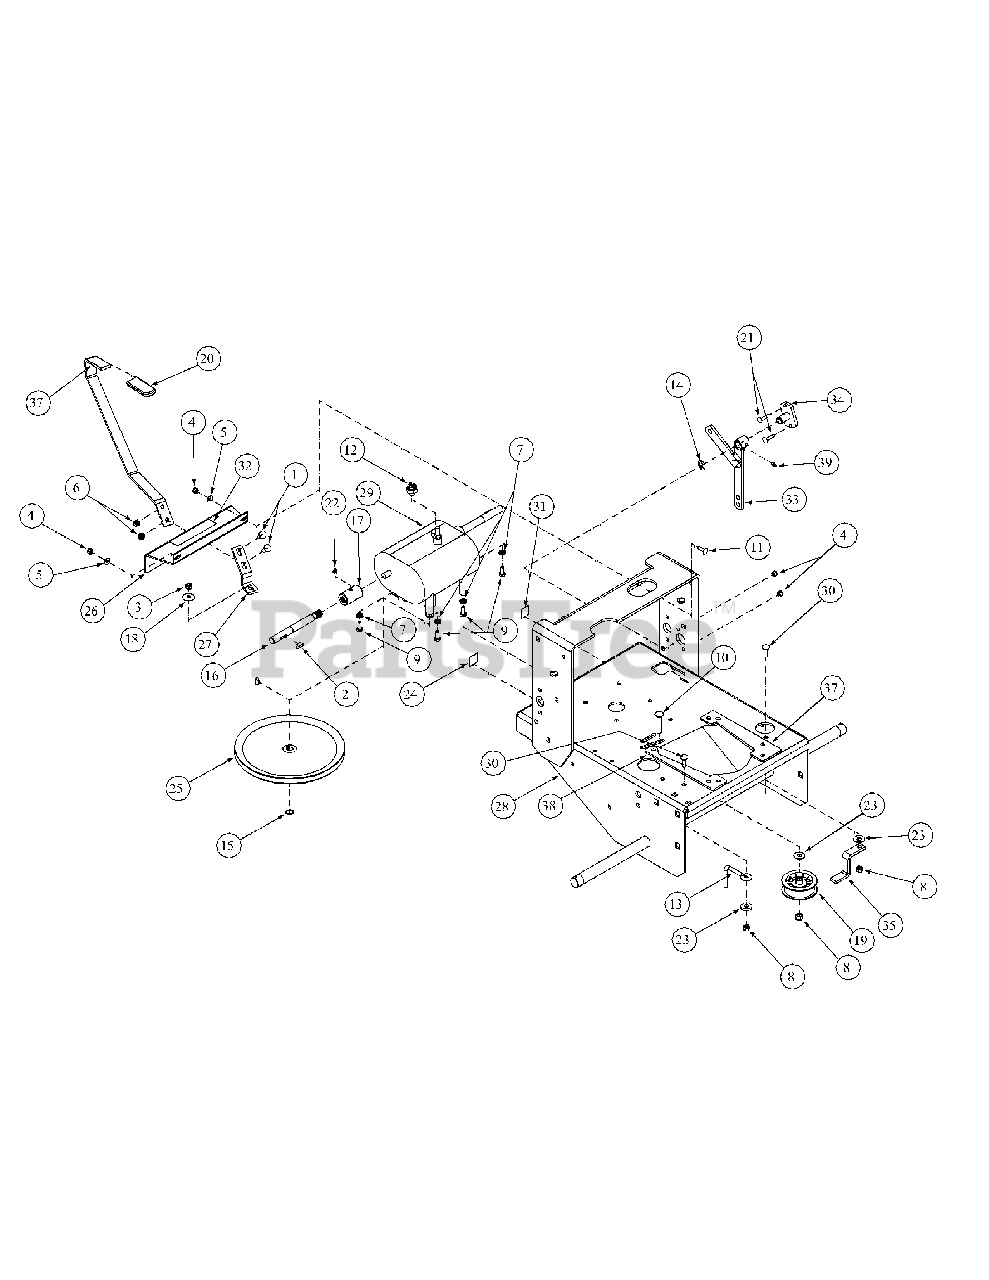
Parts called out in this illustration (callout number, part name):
1	Carriage Bolt, 5/16-18 x 1
2	Woodruff Key, 3/16 x 3/4
3	Jam Nut, Insert Lock, 3/8-24
4	Lock Nut, Nylon Insert, 1/4-20
5	Flat Washer, 1/4 Zinc
6	Nut, 5/16-18 Nylock
7	Lock Washer, 5/16 Zinc
8	Lock Nut, Nylon Insert, 3/8-16
9	Hex Cap Screw, 5/16-18 x 3/4
10	Carriage Bolt, 3/8-16 x2
11	Carriage Bolt, 1/4-20 x .750
12	Switch, WB Transmission
13	Drive Belt Guide
14	E-Ring, 5/8
15	External Retainer Ring
16	Jackshaft w/ Heavy Spline
17	Coupling w/Heavy Spline
18	Bell Washer, .39 ID x 1.13 OD x .062
19	Flat Idler Pulley w/Adapter
20	Grip, .250 x 1 x 3-1/2, Yellow
21	Carriage Bolt, 1/4-20 x 1.00
22	Grease Fitting, 1/4-28 x 3/16
23	Idler Washer
24	Decal "Made In America
25	Transmission Pulley
27	Shift Arm
28	Engine Deck Assembly
29	Transmission, 5 Speed
30	Carriage Bolt, 3/8 -16 x 1.25
31	Label, Warning, Open Belt Drive
32	Label, Mower Instruction
33	Clutch, Bellecrank Weldment
34	Bellecrank Pivot, Weldment
35	Engine Belt Guide
37	Engine Spacer, LH
38	Engine Spacer, RH
39	Grease Fitting, 1/4-28 x 3/16
